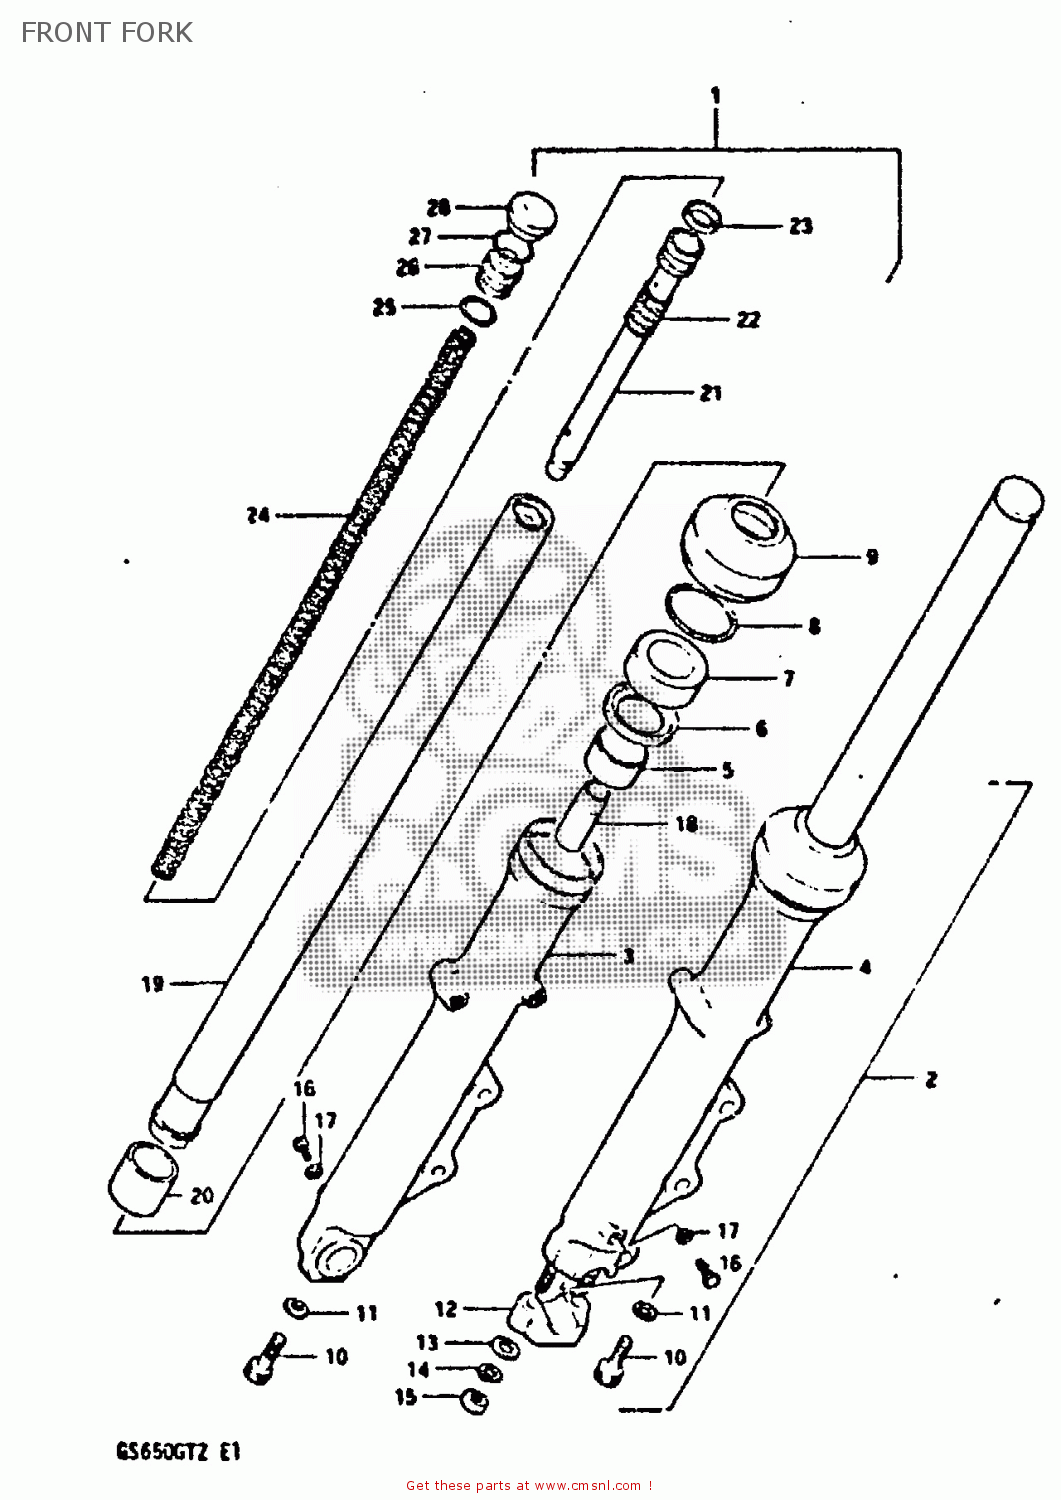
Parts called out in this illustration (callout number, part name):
1	DAMPER ASSY, RH
2	DAMPER ASSY, LH
3	OUTER TUBE, RH
4	OUTER TUBE, LH
5	GUIDE,FORK INNER TUBE
6	SPACER,SEAL
7	OIL SEAL,FRONT FORK
8	RING, STOPPER
9	BOOT
10	BOLT(8X27)
11	GASKET (NAS)
12	HOLDER,AXLE
13	WASHER
14	LOCK WASHER
15	NUT
16	BOLT(6X8)
17	GASKET,DRAIN,PLUG (NAS)
18	PIECE,OIL LOCK
19	INNER TUBE
20	PISTON
21	CYLINDER
22	SPRING,FORK REBOUND
23	RING,PISTON
24	SPRING
25	O RING
26	SEAT,FRONT FORK SPRING
27	STOPPER RING,FORK SPRING
28	CAP,FRONT FORK
